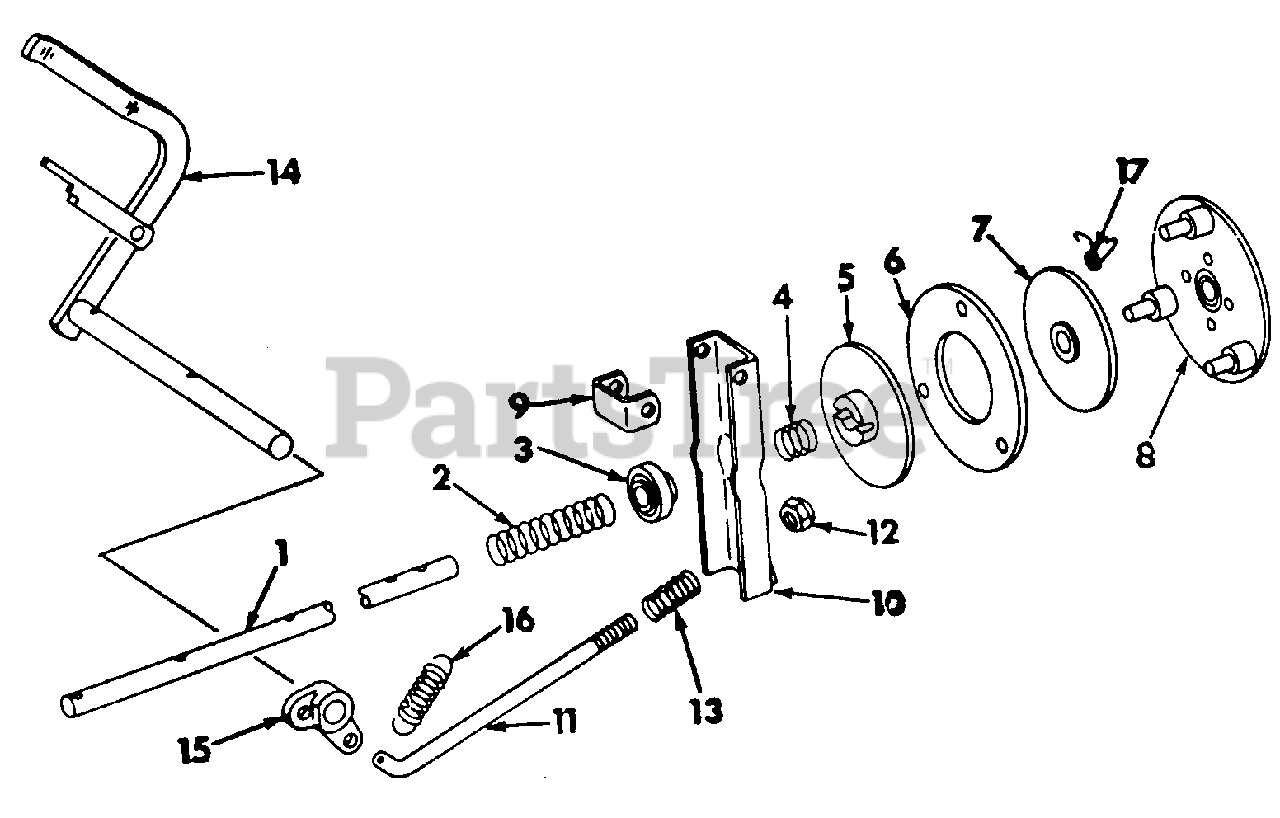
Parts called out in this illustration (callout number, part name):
1	Package, Clutch Shaft Service
2	Spring, Clutch Loading
3	Bearing, Clutch Throwout Ball
4	Spring, Clutch Teasing
5	Hub Assy, Pressure Plate
6	Disc, Clutch Driving
7	Hub Assy, Pressure Plate Locating
8	Plate Assy, Driving
9	Bracket, Clutch Operating Yoke
10	Lever, Clutch Release
11	Rod, Clutch Release
12	Nut, 3/8-24 Hex Self-Align
13	Spring, Clutch Release Rod
14	Pedal Assy, Clutch and Brake
15	Arm, Clutch and Brake Pedal
16	Spring, Clutch Pedal Return
17	Spring, Clutch Driving Disc
